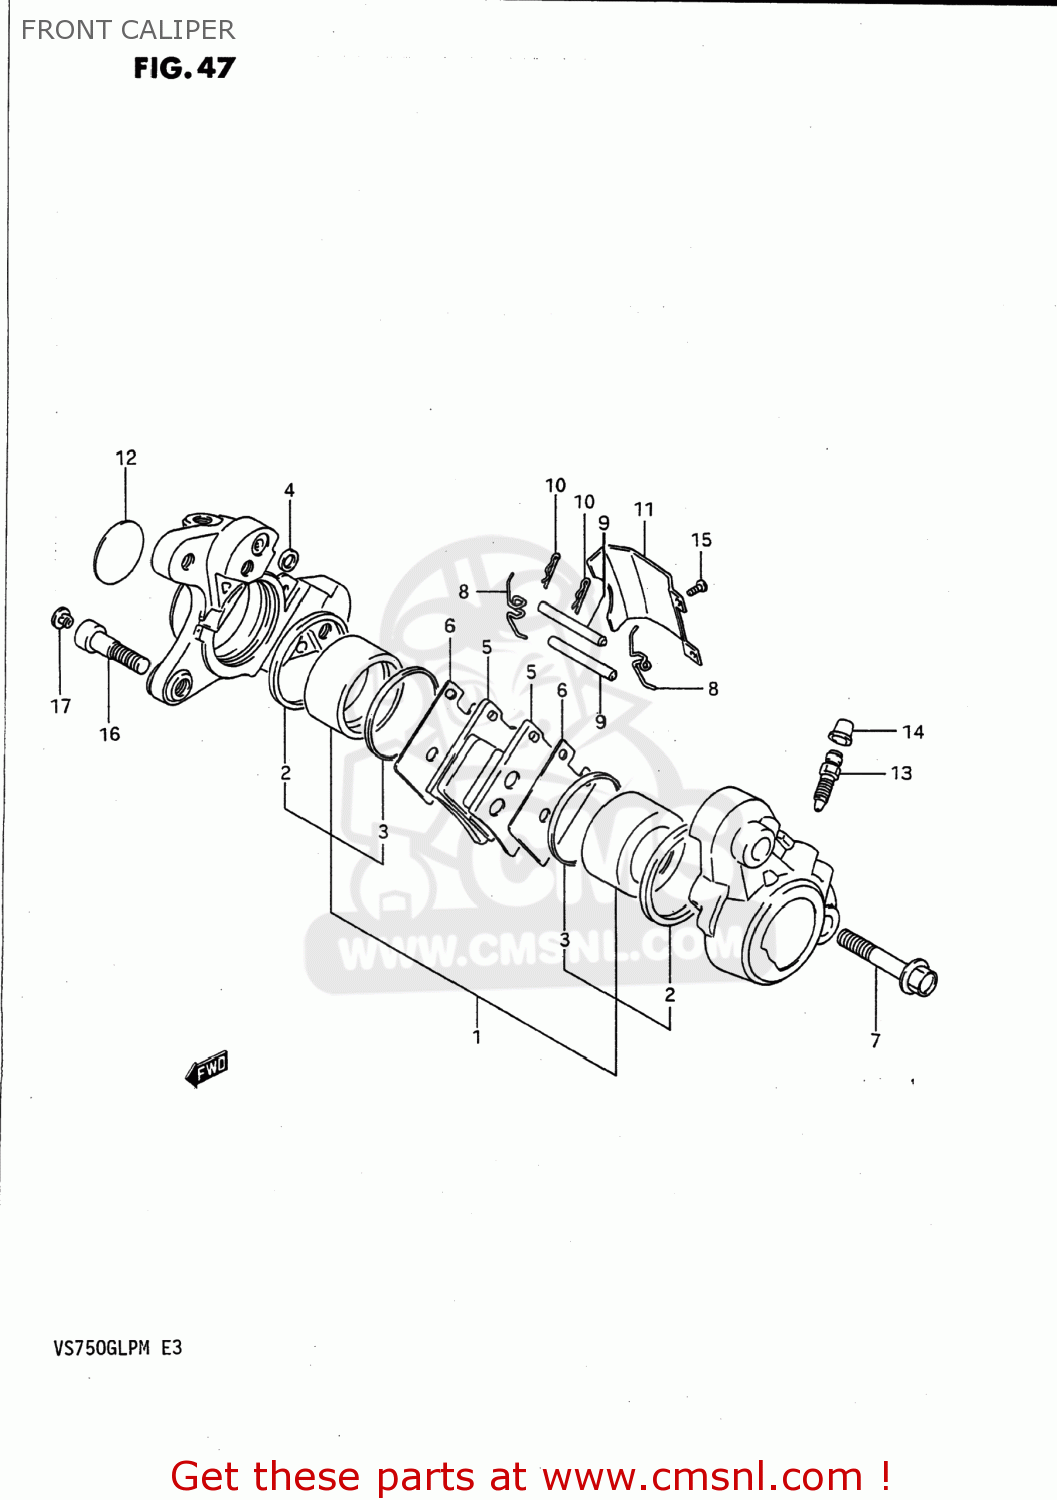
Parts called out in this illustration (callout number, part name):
1	PISTON SET
2	SEAL,FR CALIPE
3	BOOT,PISTON
4	SEAL,JOINT
5	PAD
6	SHIM,PAD
7	BOLT,HOUSING
8	SPRING
9	PIN,PAD
10	CLIP,PAD PIN
11	COVER,CALIPER
12	CAP,CALIPER
13	BLEEDER
14	CAP,BREATHER
15	SCREW,CALIPER COVER (4X
16	BOLT(10X33)
17	CAP(OD:12)
